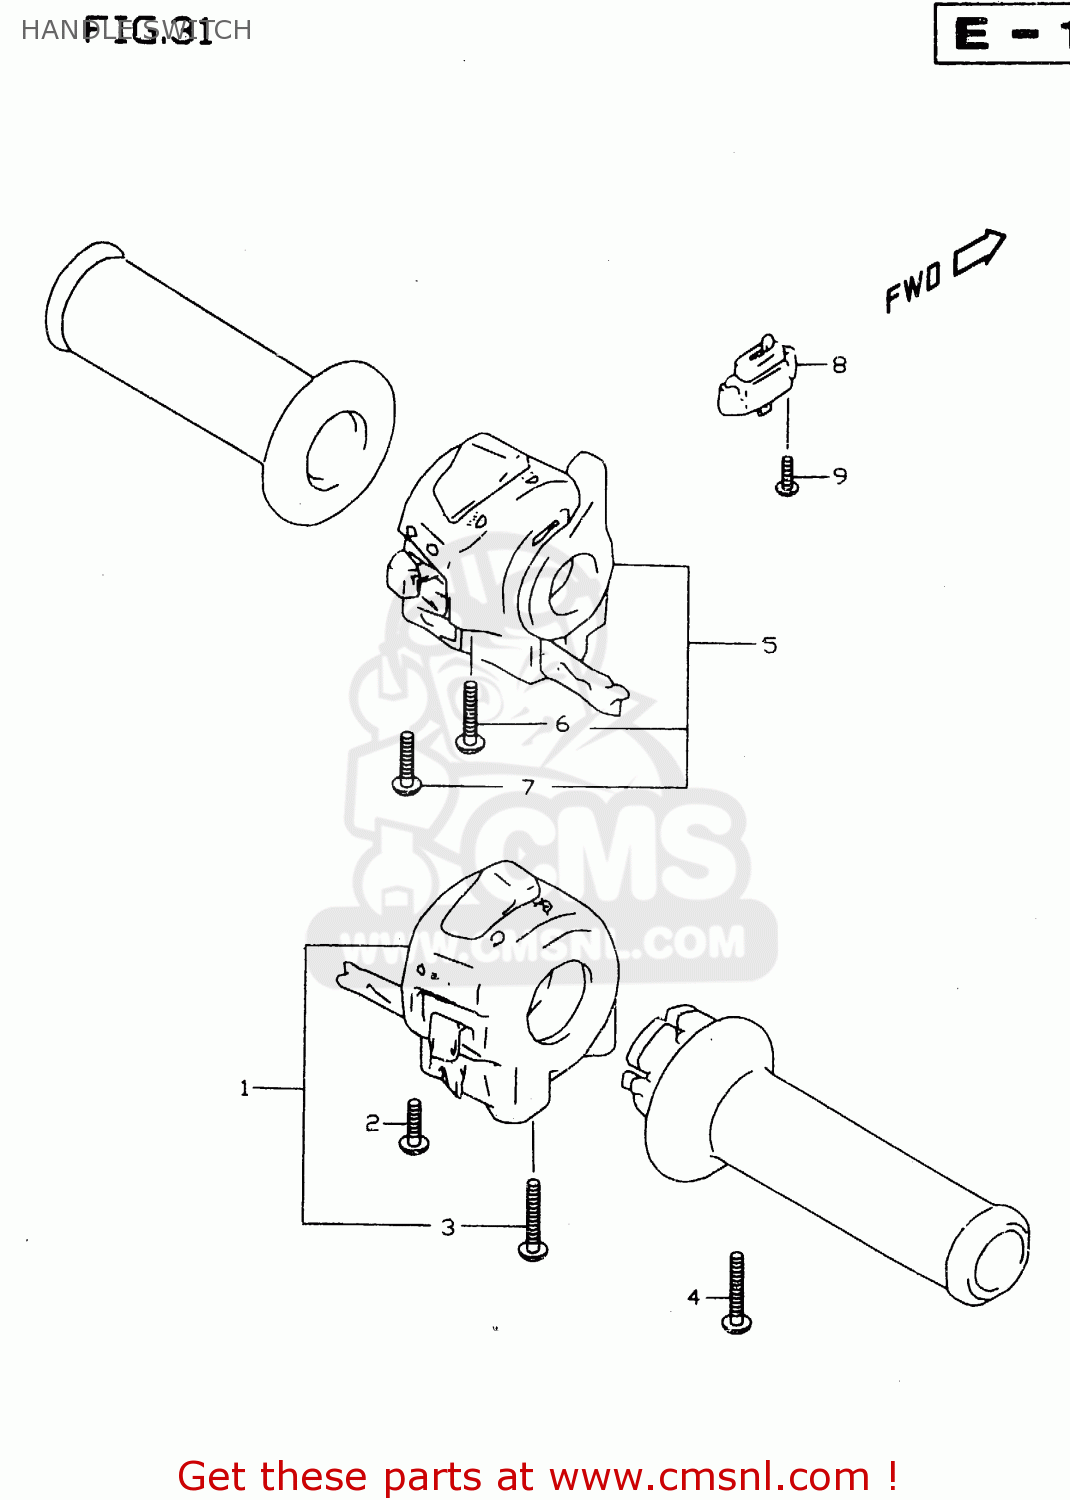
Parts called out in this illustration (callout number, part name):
1	SWITCH ASSY,HANDLE,R
2	SCREW
3	SCREW
4	SCREW
5	SWITCH ASSY,HANDLE,L
6	SCREW
7	SCREW
8	SWITCH ASSY,CLUTCH
9	SCREW
